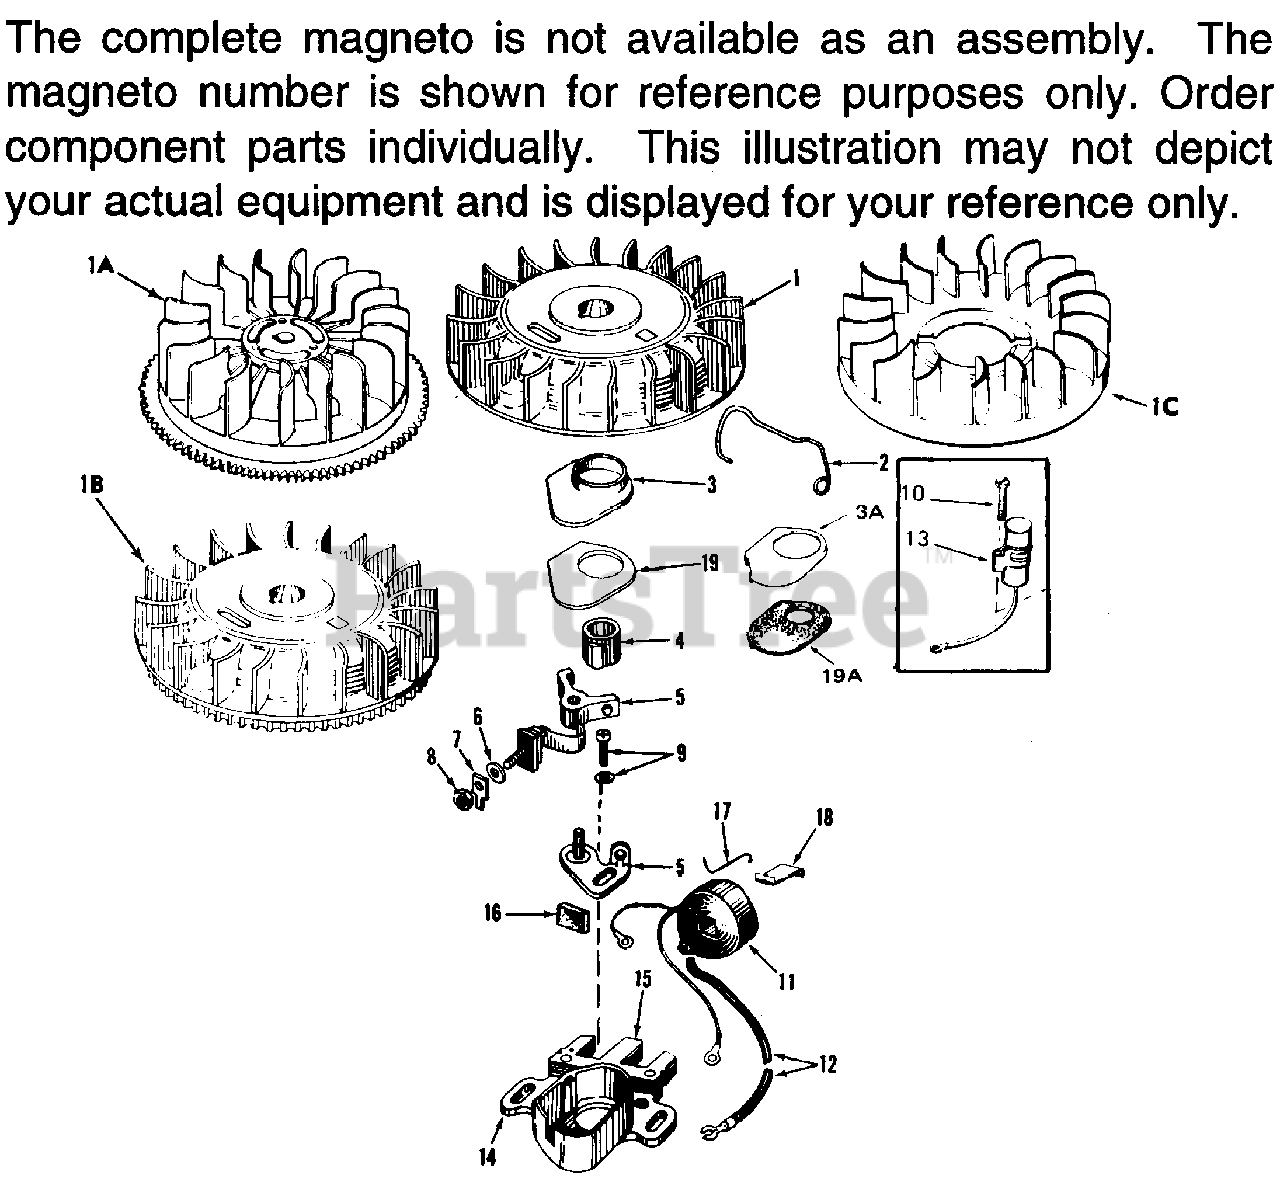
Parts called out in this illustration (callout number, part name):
1	Flywheel (Incl. 1B, 3 & 19)
2	Spring, Breaker box dust cover
3	Cover, Breaker box dust
4	Cam, Breaker
5	Breaker Points (also available in Pac kaged Part #740037B)
6	Washer, Terminal
7	Tab, Ground terminal
8	Nut, Terminal
9	Screw & Washer, Breaker
10	Screw, Condenser
11	Coil Assy. (Incl. 12)
12	Wire, Lead
13	Condenser (also available in Packaged Part #740037B)
14	Core & Plate
15	Stator Assy. Incl. 2, 3, 5 thru 11, 1 3, 14, 16, 17 & 19
16	Felt, Cam wiper
17	Clip, Coil locking
19	Gasket, Breaker box
